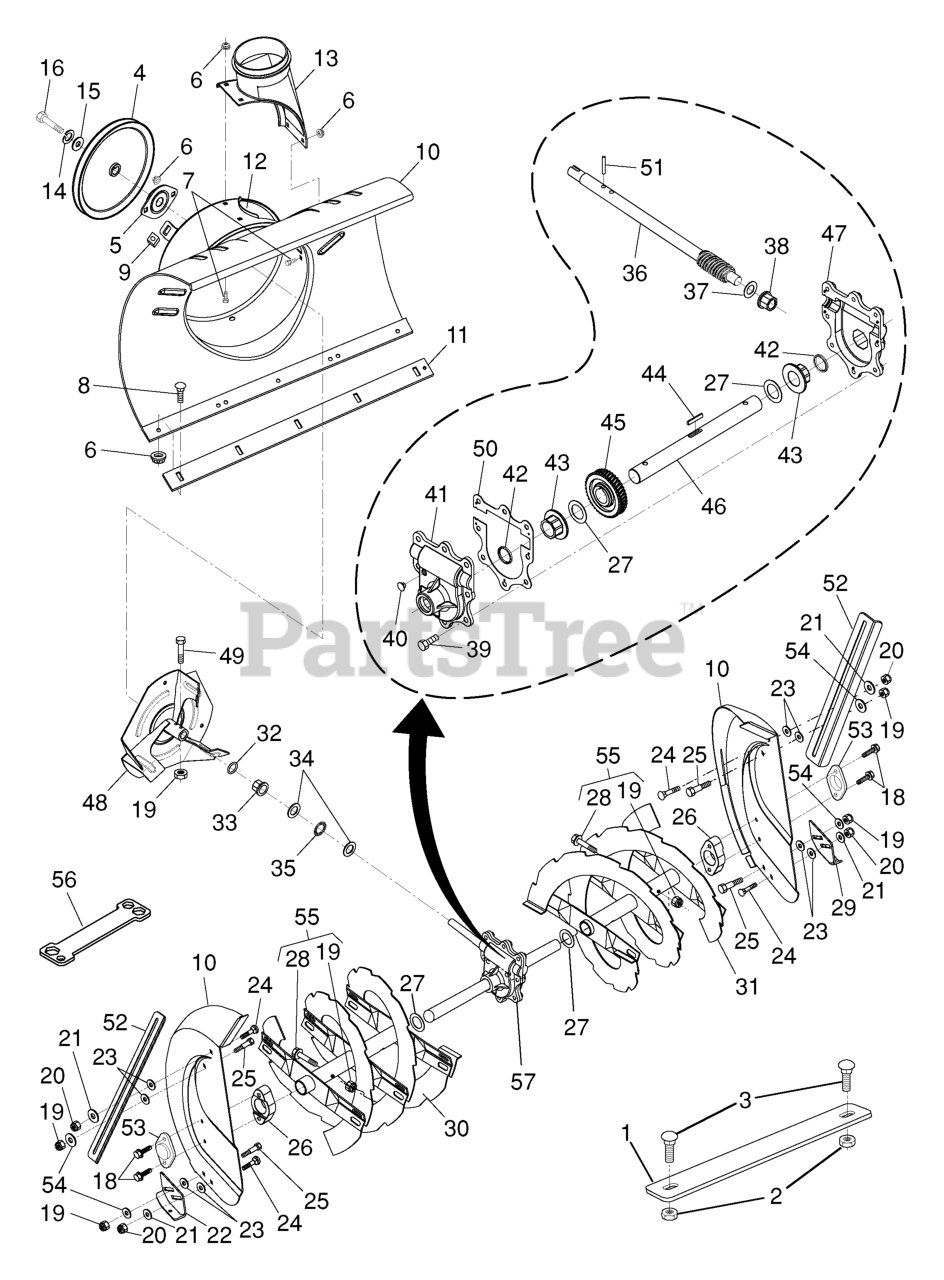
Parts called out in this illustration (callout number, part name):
1	WEIGHT AUGER HOUSING 30
2	LOCKNUT 5/16-18
3	BOLT.CARRIAGE.5/16-18
4	PULLEY, IMPELLER
5	BEARING FLANGE
6	NUT.FLANGE.5/16
7	BOLT.CARRIAGE.5/16-18X
8	BOLT
9	NUT, CAGE 3/8-16
10	HOUSING, AUGER
11	BAR, SCRAPER 30"
12	BRACKET, CORNER DISCHARGE
13	BASE DISCHARGE CHUTE
14	WASHER, FLAT
15	WASHER.LOCK.HVY.HLCL.SPR.5/16
16	Screw, Hex Head 5/16-18 x 3/4
18	SCREW, HEX HD 5/16X1
19	LOCKNUT.NYLOC.1/4-20
20	NUT.71038.31-18.HEX.NYLOCK
21	WASHER.20X8.5
22	SKID PLATE RH
23	WASHER, NYLON FRICTION
24	BOLT
25	SHOULDER BOLT
26	BEARING RETAINER, PLASTIC
27	WASHER TRUST 1"
28	BOLT.SHOULDER.SHEAR.1/4-20.
29	SKID PLATE LH
30	AUGR.ASM.30".RH.PNT
31	AUGR.ASM.30".LH.PNT
33	BUSHING FLANGE 3/4
34	WASHER, THRUST 3/4
35	BEARING TRUST 3/4 NTA-1220
36	SHAFT, IMPELLER
37	WASHER, THRUST 5/8
38	BUSHING.FLANGE.(.625X.75)
39	SELF-TAPPING SCREW 5/16-18X3/4
40	PLUG.AUGER.GEAR.BOX.SNOW
41	HOUSING.GEARBOX.RH.SNOW
43	BUSHING FLANGE 1"
44	KEY, SQUARE 1/4 X .875
45	WORM GEAR
46	SHAFT, AUGER
47	LH GEARBOX HOUSING
48	IMPELLER ASSY
49	SCREW.HEX.HD1/4-20X
50	GASKET.AUGER.GEARBOX
51	PIN, ROLL 3/16 X 1-1/8
52	DRIFT CUTTER BAR
53	BEARING.BALL.AUGER.SHAFT
54	WASHER
55	KIT, BOLT, SHEAR
56	RP WRENCH, SNOWTHROWER
57	AUGER GEARBOX (COMPLETE)
